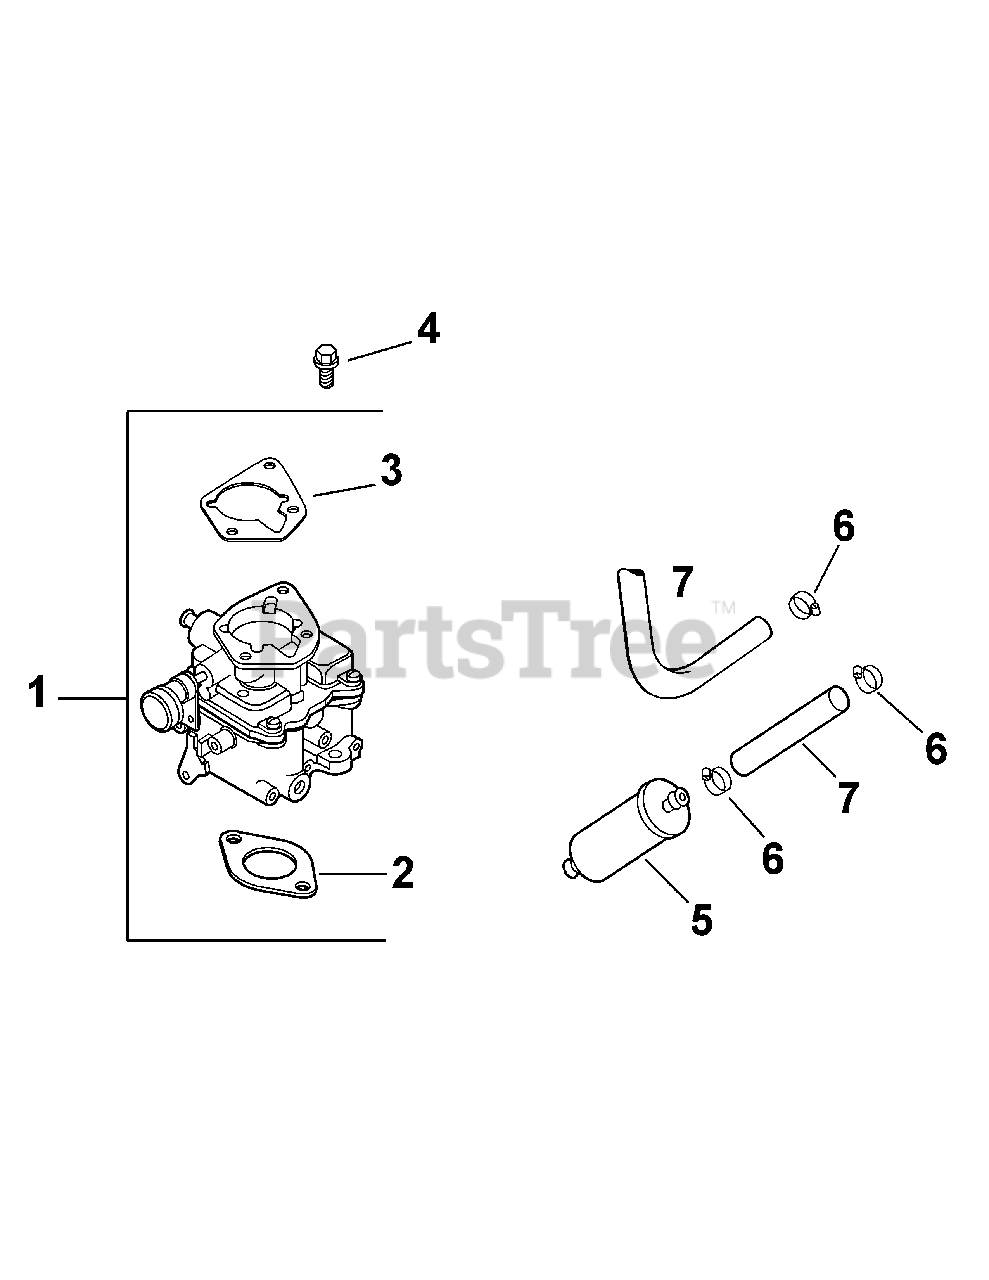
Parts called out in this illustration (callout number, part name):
1	Kit, carb w/gasket
2	Gasket, air cleaner base
3	Gasket, carburetor
4	Screw, hex flange M6x1.0x25
5	Filter, fuel
6	Clamp, hose
7	Line, fuel 24" - cut to length
